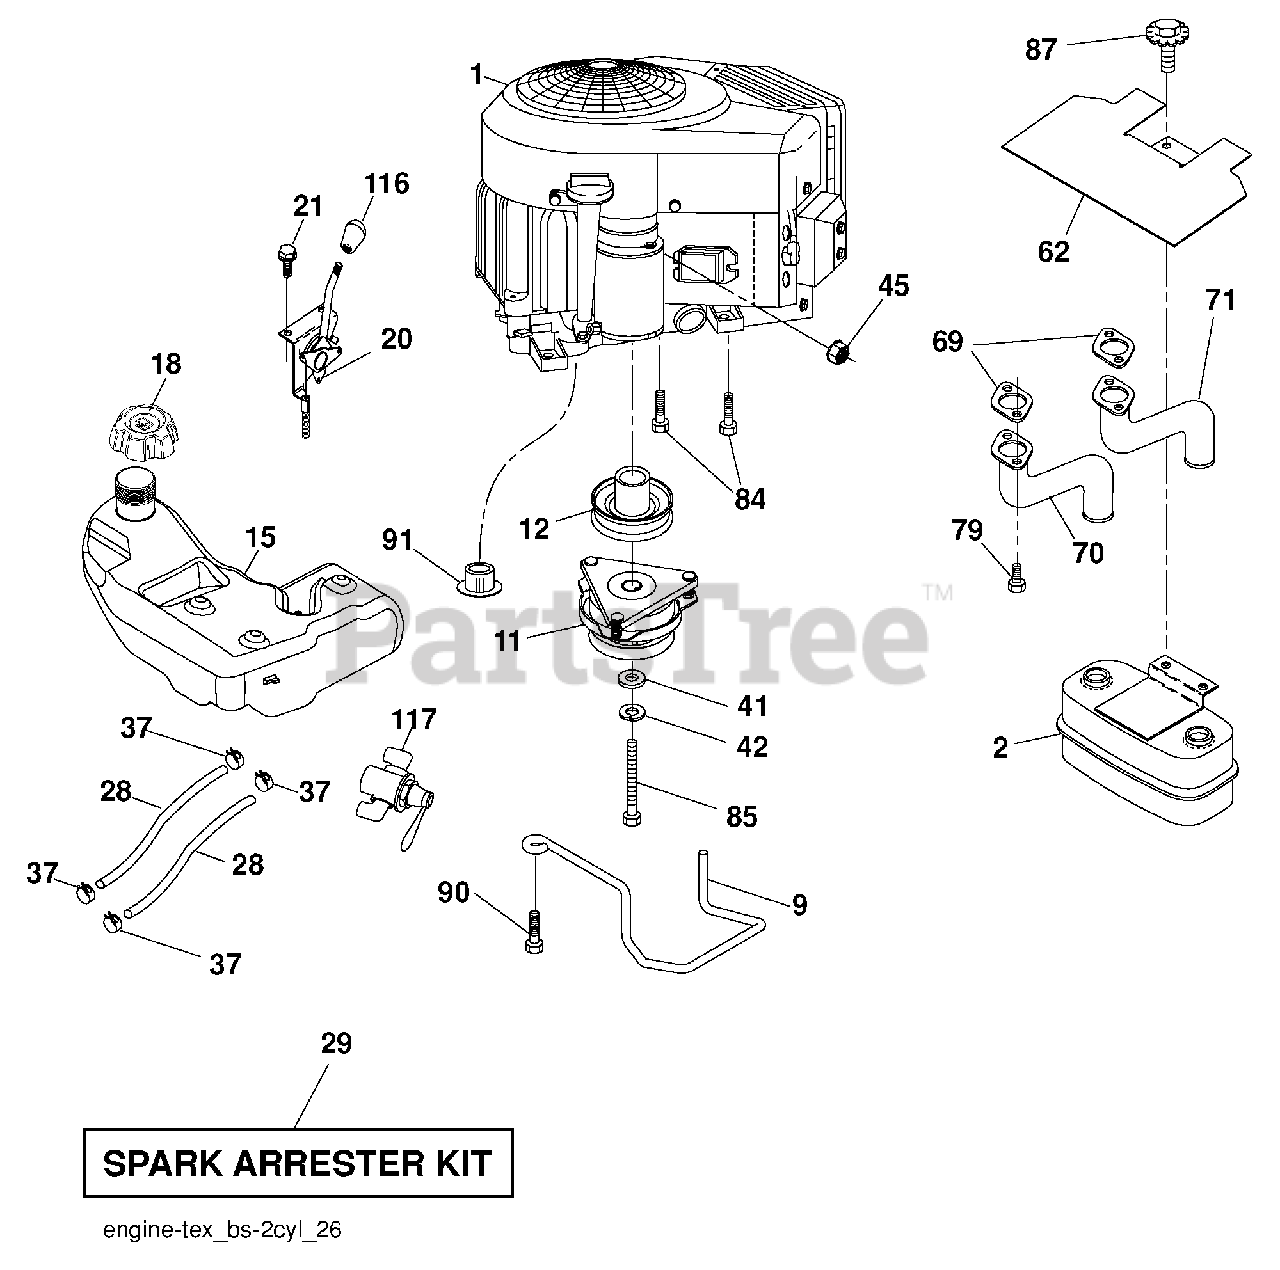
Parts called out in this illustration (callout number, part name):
9	Keeper Asm. Belt Engine
11	Clutch Electric
12	Pulley Engine
15	Tank Fuel 4R
18	Cap Asm
20	Control Throttle
21	Screw #10 x 0.750 BOS Thread
28	Fuel Line
29	Spark Arrester Kit
37	Clamp Hose
41	Washer 1-1/2 OD x 15/32 ID x .250
42	Washer Lock 7/16
45	Nut Keps Hex 1/4-20 unc
62	Shield Heat Muffler
70	Tube Exhaust LH
71	Tube Exhaust RH
79	Screw Socket HD 5/16-18 x 1
84	Screw 3/8-16 x 1-1/4
85	Bolt 7/16-20 x 3.75 Gr. 5
87	Bolt 5/16-18 unc x 1 w/Sems
90	Screw 3/8-16 x 1
116	Knob Soft Touch
117	Valve Fuel Reserve
